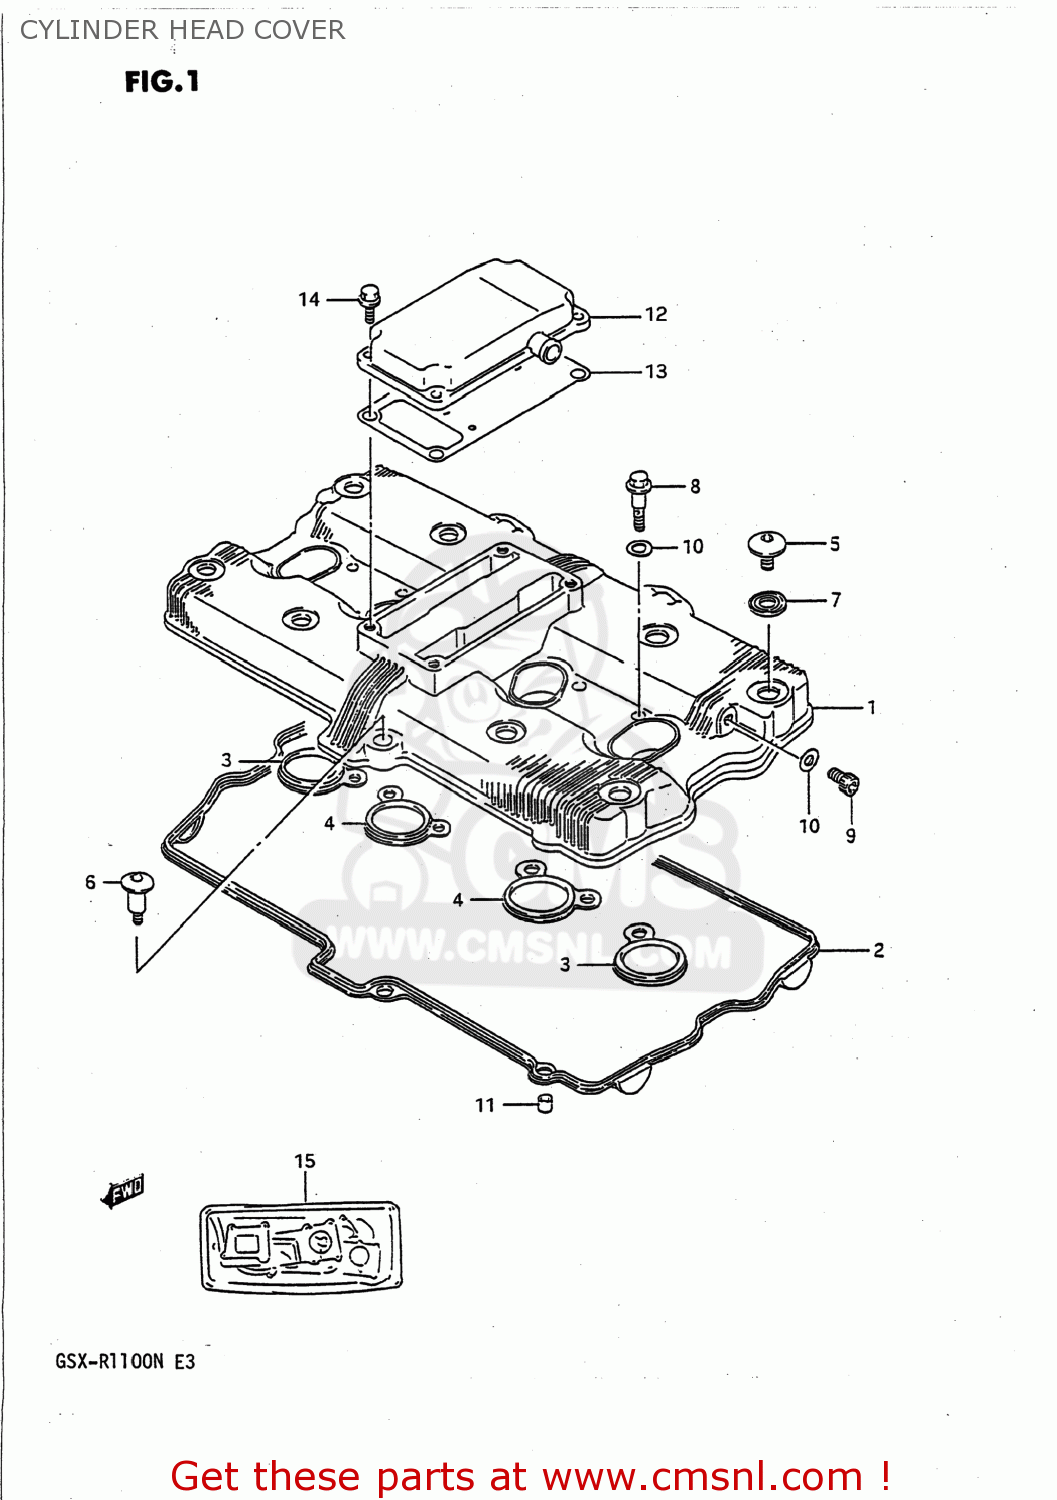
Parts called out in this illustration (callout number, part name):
1	COVER,CYLINDER HEAD
2	GASKET,CYLINDER HEAD COVER (NAS)
3	GASKET,HEAD COVER NO.2 (NAS)
4	GASKET,HEAD COVER NO.3 (NAS)
5	BOLT(7X17.5)
6	BOLT(7X31)
7	WASHER(10.6X25.5X2.3)
8	BOLT,UNION 8X35
9	PLUG, HEAD COVER
10	GASKET 8.2X14X1 (NAS)
11	PIN
12	COVER,BREATHER
13	GASKET,BREATHER (NAS)
14	BOLT 6X20
15	GASKET SET (NAS)
